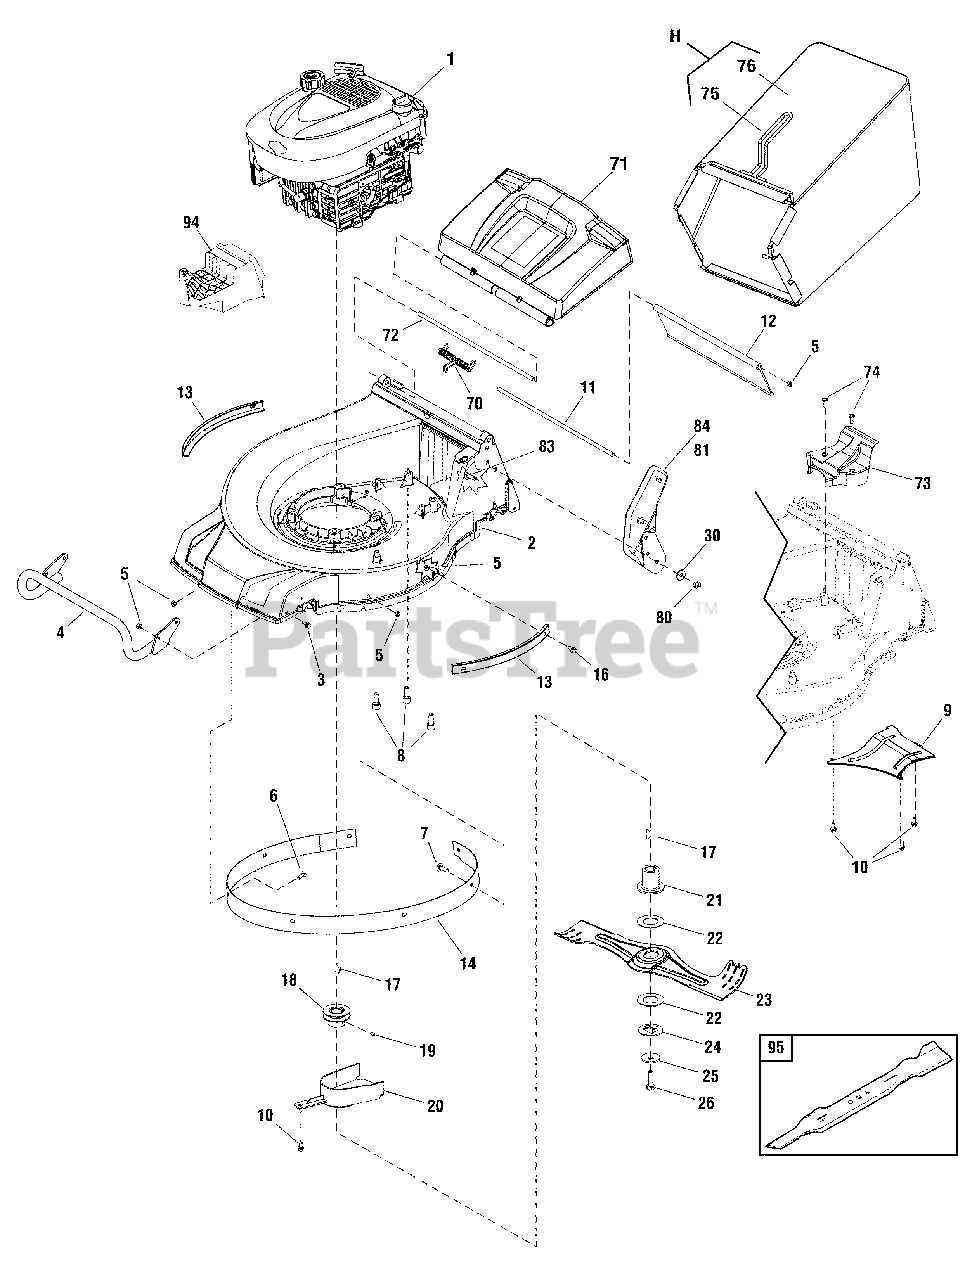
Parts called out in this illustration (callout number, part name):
1	* ENGINE, 850 Series, Briggs & Stratton
2	DECK, 19"
3	BOLT, Hex Flange
4	BUMPER, 19"
5	NUT, Hex, Nylon Insert, Torque Type
6	SCREW, Truss Head, Cross Recessed
7	SCREW, Truss Head, Cross Recessed
8	SCREW, Inner Hexagon, Round Head, Tapping
9	DEFLECTOR, Lower
10	SCREW, Hex Flange, Tapping
11	SHAFT, Rear Deflector
12	DEFLECTOR, Rear
13	SHIELD, Outer
14	SHIELD, Inner Ring
16	BOLT, Hex Flange
17	KEY, Woodruff
18	SCREW, Allen
19	SHIELD, Lower Belt
20	DISC, Friction
21	BLADE, 19"
22	CLIP
23	SPRING, Dishing
24	BOLT, Blade
25	WASHER, Flat, C-Class
26	SPRING, Torsion
30	COVER, Rear
70	SHAFT, Rear Cover
71	SHIELD, Upper Pulley
72	SCREW, Inner Hexagon Tapping
73	GRASS CATCHER ASSEMBLY
74	FRAME, Grass Catcher
75	NUT, Hex, Nylon Insert, Torque Type
76	BRACKET, Right
80	BOLT, Carriage
81	BRACKET, Left
83	PLUG, Mulch, 19"
84	BLADE, Mulch, 19"
94	PULLEY, Engine
95	ADAPTOR, Blade
H	BAG, Grass Catcher
